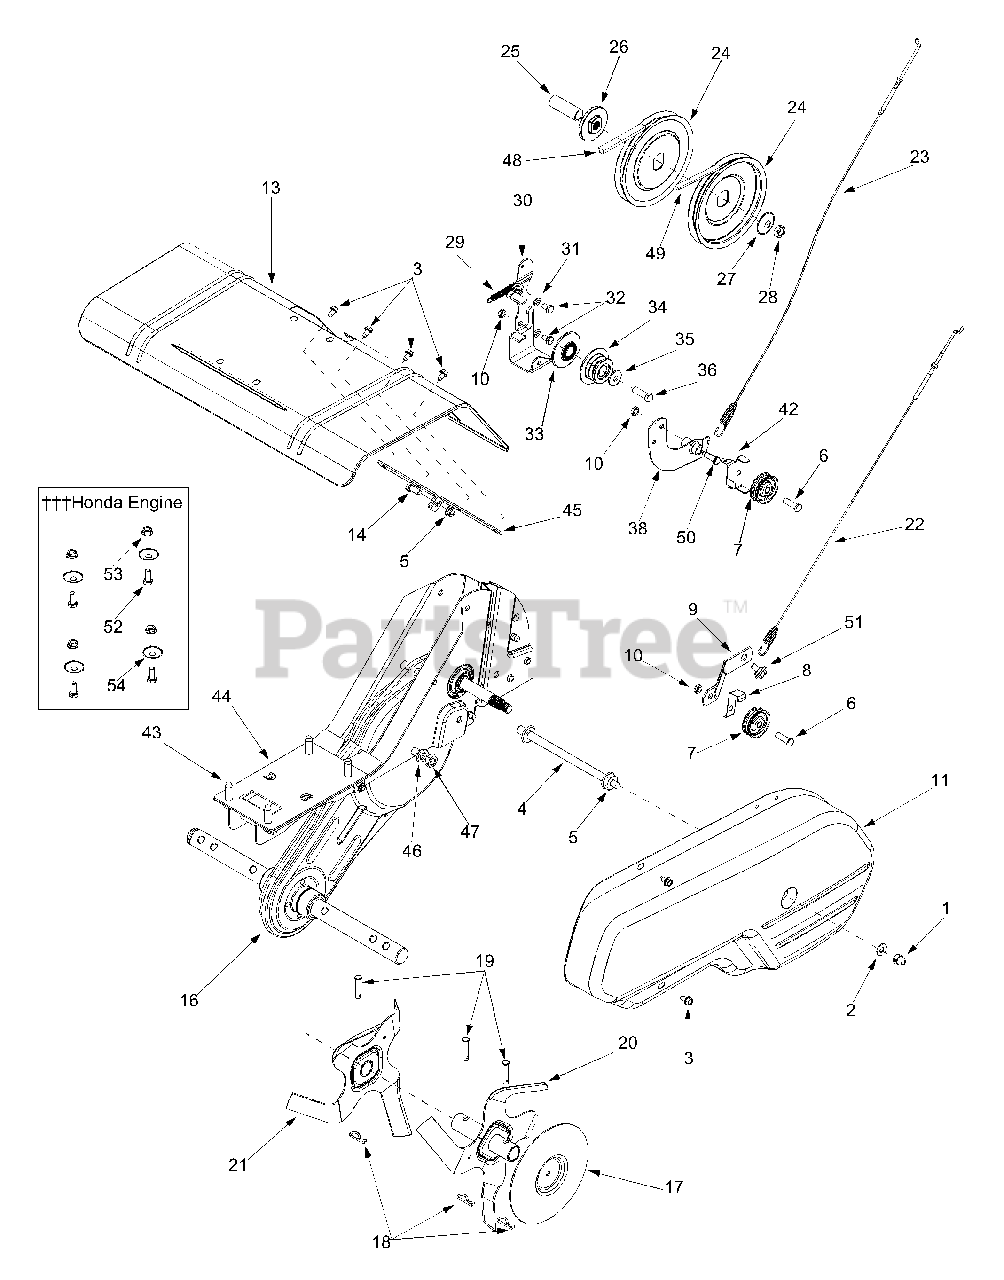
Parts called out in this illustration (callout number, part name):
1	Hex L-Stop nut 1/4-28
2	Flat Wash .266" I.D. x .625" O.D.
3	Hex Washer TT-Tap Scr. 1/4-20 x.5"
4	Belt Cover Bolt
5	Hex Flange Top L-Nut 5/16-18 (Gr.5)
6	Hex Hd. Scr. 3/8-16 x 1.25" Lg. (Gr.5)
7	Flat Idler Pulley 2.12" O.D.
8	Idler Belt Keeper
10	Hex Cent. Jam Nut 3/8-16 Thd.
14	Hex Hd. Cap Scr. 5/16-18 x.75" Lg
16	Chain Case Assembly Complete
18	Internal Cotter Pin
19	Clevis Pin
22	Forward Clutch Cable
23	Reverse Clutch Cable
24	Fl-Pulley 6" Dia.
25	Spacer .64" Dia. x 2.4" Lg.
26	Pulley Mounting Adapter
27	Bell-Wash .525" I.D. x 1.5" O.D.
28	Hex Jam Nut 1/2-20 Thd. (Gr. 5)
29	Return Spring
31	Lock Washer 5/16
32	Hex Bolt 5/16-24 x .625"
33	Engine Inner Half Pulley
34	Reverse Engine Pulley
35	Bell Washer .396" I.D. x 1/14" O.D.
36	Hex Bolt 3/8-24 x 1.00"
38	Reverse Arm Assembly
43	Hex L-Wash. TT-Tap 3/8-16 x 1.25"
46	L-Wash. 7/16" I.D.
47	Hex Nut 7/16-20 Thd.
48	V-Belt (Forward) 1/2 x 41.9"
49	V-Belt (Reverse) 3/8 x 45.68"
50	Shld. Screw.498 x 1.445
51	Shld. Screw.560 x.165
52	Screw 5/16-18 x 1.50
53	Hex Nut 5/16-18
54	Bell Washer
